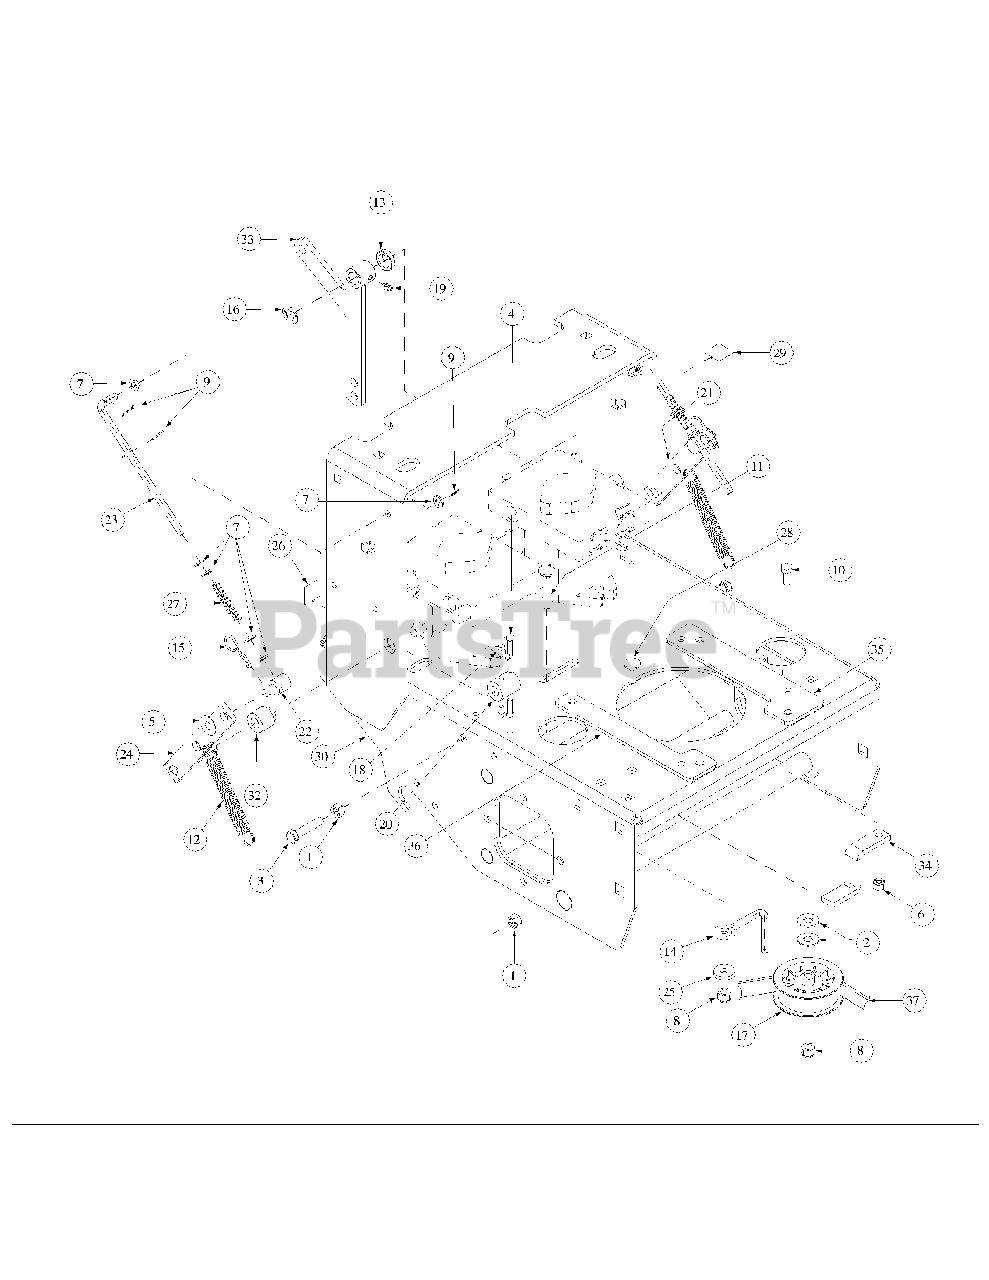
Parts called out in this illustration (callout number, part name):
1	Nut, Hex, 3/8-16 Grade C
2	Flat Washer, USS 3/8 Zinc
3	Cap Screw, 3/8-16 x 1-3/4" Grade 5
4	Cap Screw, Square Head Set, 1/4-20
5	Flat Washer, 3/8, SAE, Zinc/Yellow
6	Nut, 5/16-18, Nylock
7	Flat Washer, SAE Grade 8 5/16, Zinc
8	Nut, L, Nylon Insert, 3/8-16 Grade A
9	Cotter Pin 3/32 x 3/4, Zinc
10	Cap Screw,Standard, 5/16-18 x 1.0, Grade 5
11	Carriage Bolt, 3/8-16 x 2 Grade 5
12	Spring, Music Wire, LE-093G-9, Plated
13	Spacer, Blade Nom, 5/8 ID 1/4 Thick
14	Guide, Traction Drive Belt
15	Pin, Hair 3/8"-1/2"
16	E-Ring, 5/8" #5113-62
17	Pulley, Flat Idler W/Adaptor
18	Screw, Cap, Square Head Set, 1/4-20
19	Grease Fitting, 1/4-28 x 3/16 STR
20	Coupling, Trunnion
21	Hydraulic Pump, Lever Assembly, Left Handle
22	Hydraulic, Pivot
23	Rod, Safety Spring
24	Hydraulic Pump, Lever Assembly, Right Hand
25	Washer, Idler
26	Decal, "Made In America"
27	Spring
28	Carriage Bolt, 3/8-16 x 2 Grade 5
29	Label, Mower, Warn, Open Belt Drive
30	Engine Base Assembly, Hydro
32	Bushing, Pump Lever,
33	Bellcrank Clutch
34	Belt Guide, Engine, 36/42/48
35	Spacer, Engine, Left Hand
36	Spacer, Engine, Right Hand
